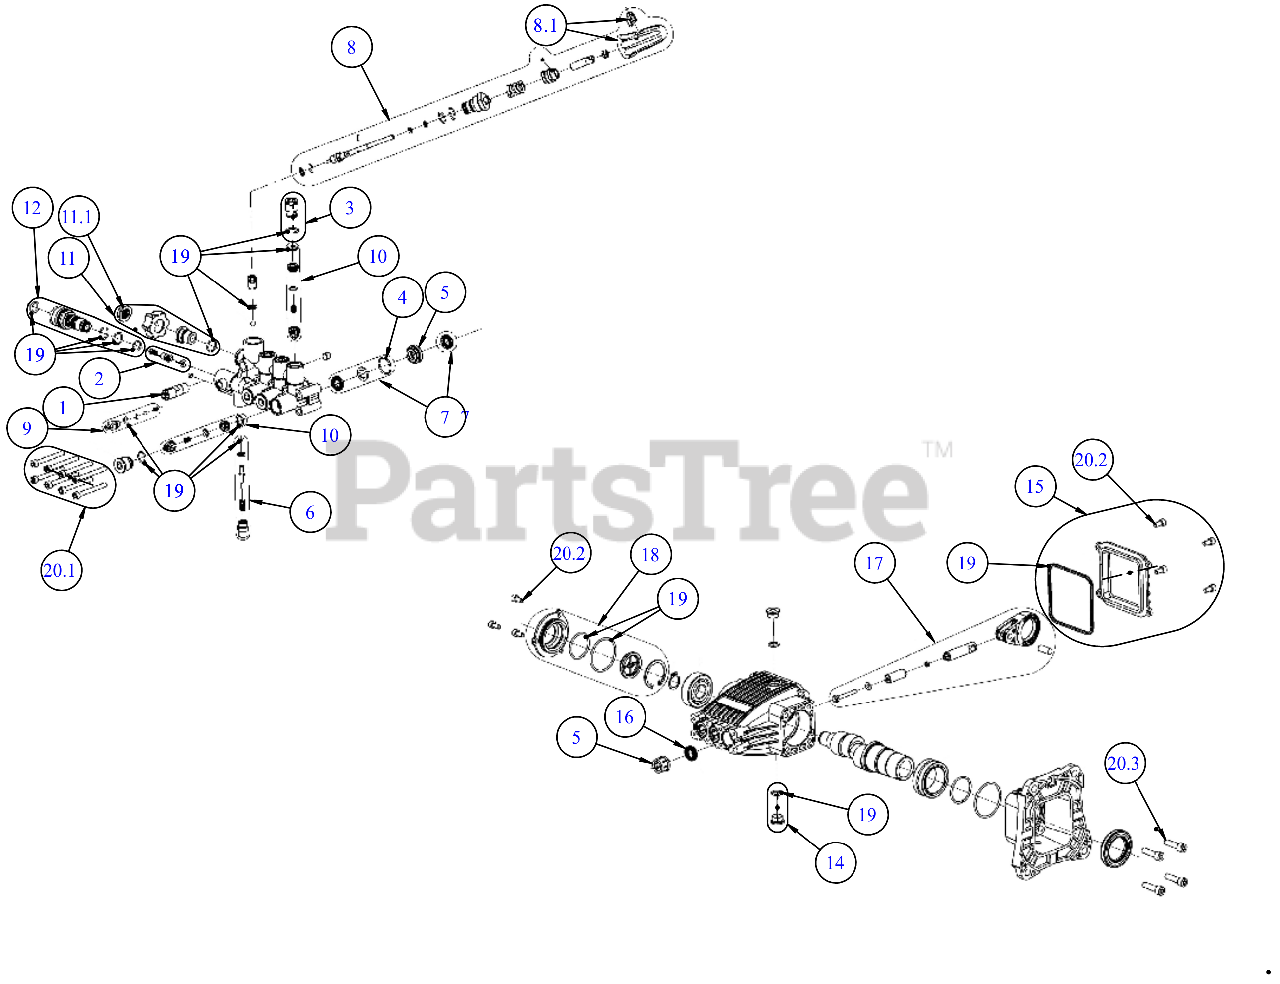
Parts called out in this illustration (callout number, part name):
1	VALVE-THERMAL RELIEF
2	UNLOADER CHECK VALVE KIT
3	VALVE CAP KIT
4	WATER SEAL RETAINER KIT
5	SEAL SPACER KIT
6	VLV KIT-PRESSURE BOOST
7	SEAL KIT-HIO PRESSURE
8	UNLOADER KIT C41
8.1	KNOB KIT-UNLOADER
9	INJECTOR KIT-SOAP
10	VALVE KIT C41
11	INLET CONNECTION KIT
11.1	WATER INLET SCREEN
12	QUICK CONNECT OUTLET
15	CRANKCASE COVER KIT
16	SEAL KIT-OIL
17	CONNECTING ROD KIT
18	CVR KIT-CRNKCASE SIDE
19	COMPLETE O-RING KIT
20	PUMP HARDWARE KIT
